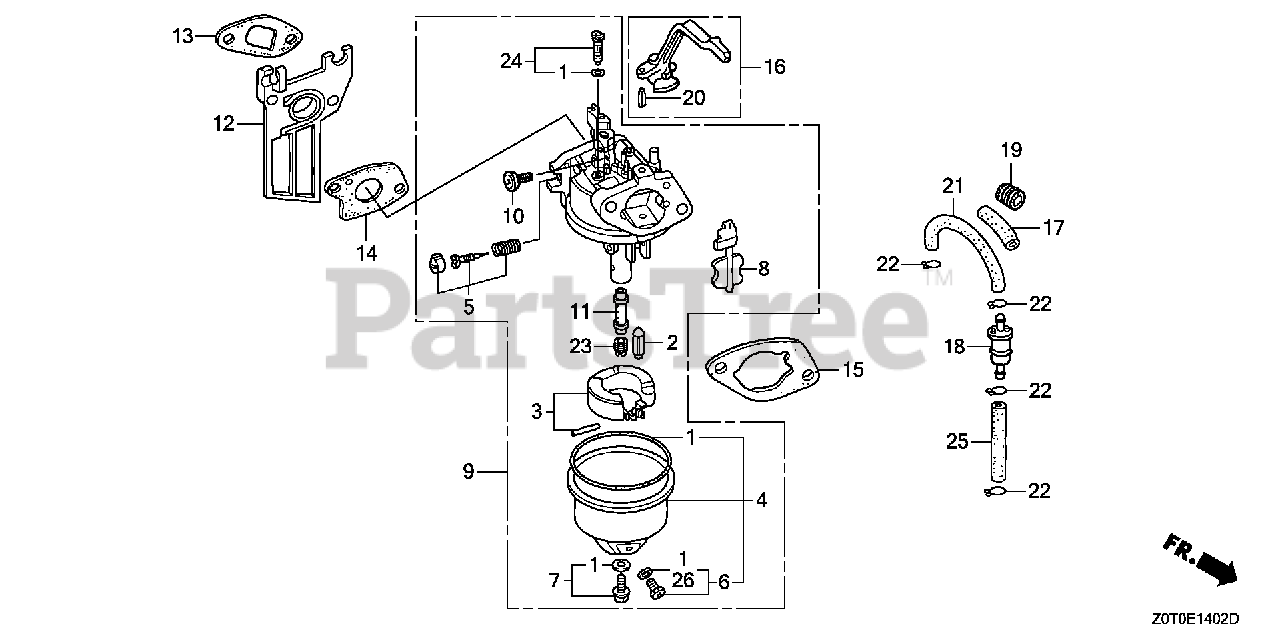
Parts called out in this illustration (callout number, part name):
1	GASKET SET
2	VALVE SET, FLOAT (SEAT NOT INCLUDED)
4	CHAMBER SET, FLOAT
5	SCREW SET, PILOT
6	SCREW SET, DRAIN
7	SCREW SET
9	CARBURETOR ASSY. (BE67K A)
10	SCREW, THROTTLE STOP
11	NOZZLE, MAIN
12	INSULATOR, CARBURETOR
13	GASKET, INSULATOR
14	GASKET, CARBURETOR
15	GASKET, AIR CLEANER
16	LEVER, CHOKE
20	PIN, SPRING (2X12)
23	JET, MAIN (#72)
23	JET, MAIN (#75)
23	JET, MAIN (#70)
24	JET SET, PILOT (#35)
